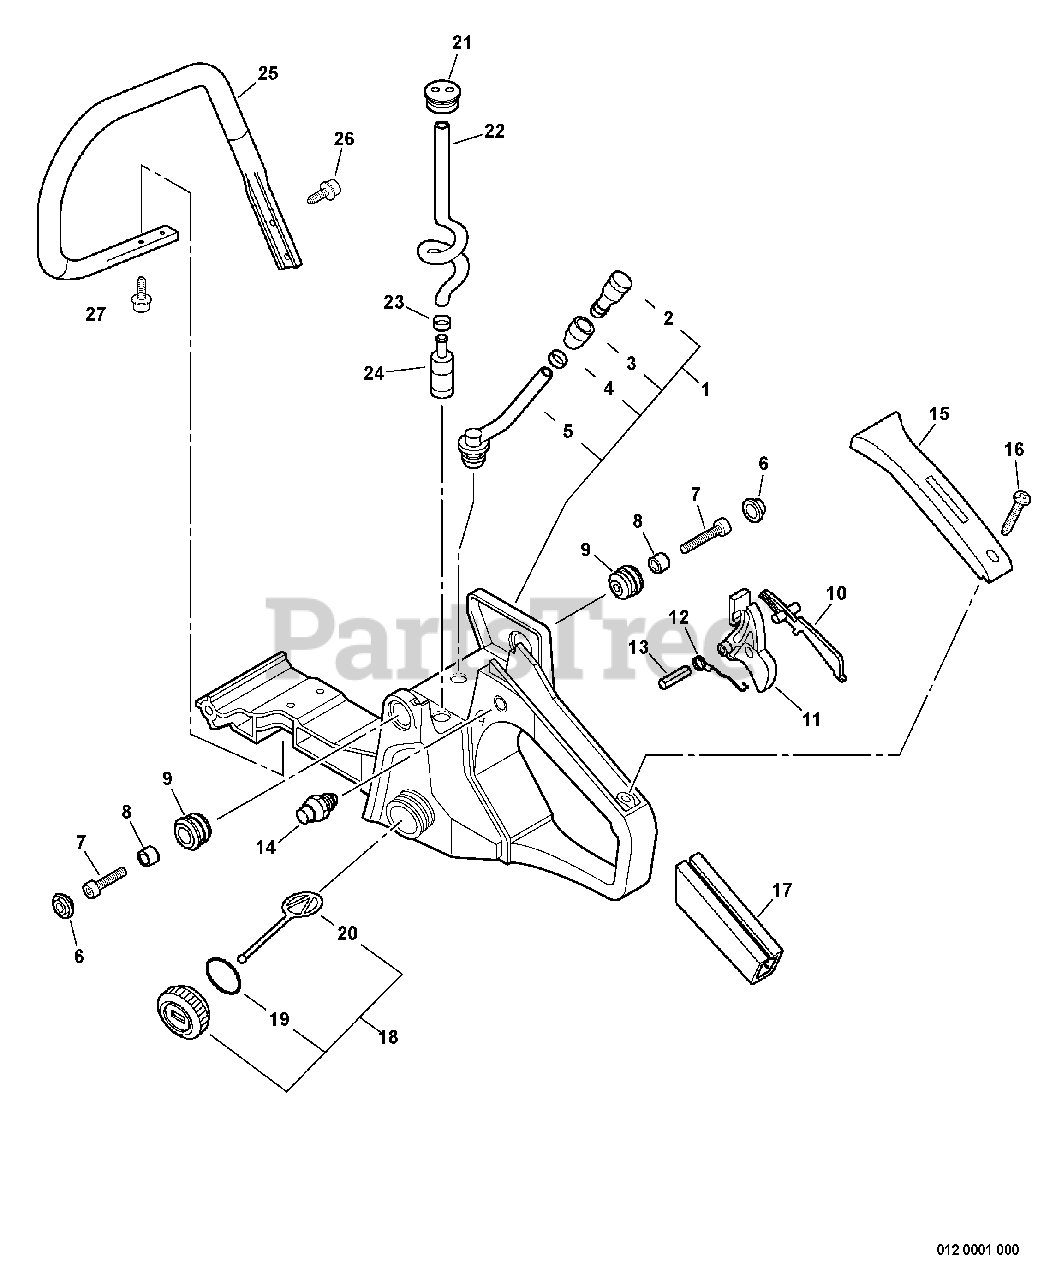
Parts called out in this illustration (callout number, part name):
1	HANDLE ASSY - REAR
2	VENT, FUEL TANK
3	COVER, VENT
4	CLIP - 6.5
5	PIPE - VENT
6	CAP, CUSHION
7	SCREW - 4X20
8	COLLAR - 4
9	CUSHION
10	LEVER, TRIGGER LOCKOUT
11	TRIGGER, THROTTLE
12	SPRING, TRIGGER
13	PIN - SPRING -- 4X30
14	LATCH, THROTTLE
15	COVER, HANDLE
16	SCREW - 4X14
17	GRIP, HANDLE
18	CAP ASSY
19	O-RING - 22
20	CONNECTOR, CAP
21	GROMMET
22	PIPE, FUEL - SPIRAL
23	CLIP - 6
24	FILTER, FUEL
25	HANDLE - FRONT
26	SCREW - 5X20 -- TAPPING
27	SCREW - 5X16
